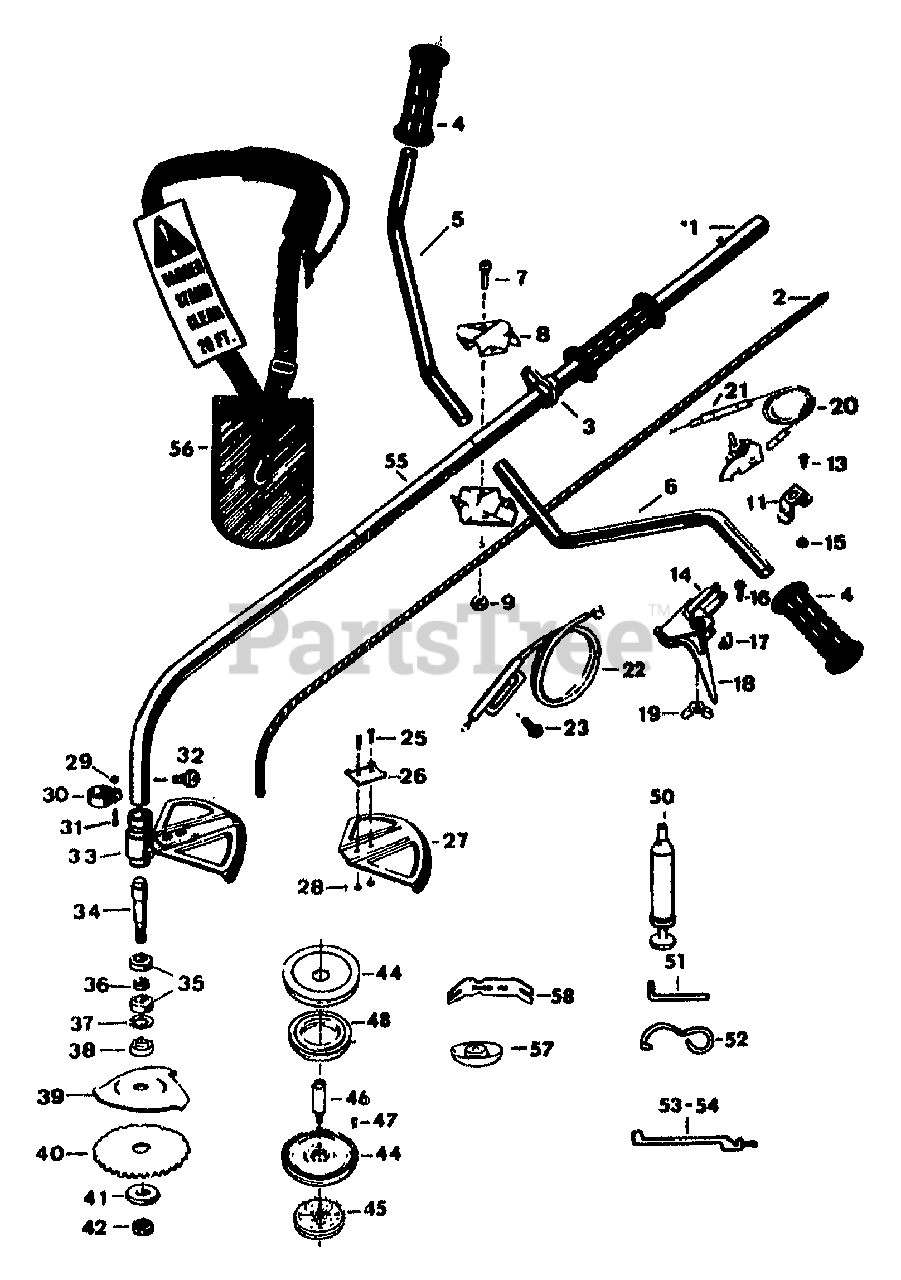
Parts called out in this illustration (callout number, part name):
1	HSG-DRIVESHAFT W/GRIP (INCL. GREASE FITTING)
2	SHAFT-DRIVE 5/16X57"
3	ASSM-SWIVEL
4	GRIP-HANDLEBAR
5	H/BAR-RH W/GRIPS
6	HANDLEBAR-LH W/GRIP
7	SCREW, SOCKET HD., 10-32, HANDLEBAR CLAMP
8	ASSM-CLAMP (INCL. 7 AND 9)
9	NUT, HEX, HANDLEBAR CLAMP
11	SWITCH-ON/OFF (INCL. BRACKET)
13	SCR-PHP M10-32X.75 ZP
14	KIT-CLAMP TRG. H205596
15	NUT-HH M10-32X.125
16	SCREW, HEX HD., 10-32X1, THROTTLE CONTROL
17	SPRING, THROTTLE CONTROL
18	ASSM-TRIGG H205532 (INCL. 16,17,19)
19	NUT, WING, 10-32, THROTTLE CONTROL
21	WIRE CONNECTOR & COVER
22	CABLE-THROTTLE
23	SCR W/SERRATED WASHER
25	SCR 1/4-20X1/2
26	CLAMP-GRASS/DUST SHIELD
27	ASSM-GRASS/DUST SHIELD
28	NUT-HF/LK 1/4-20 ZP
29	NUT-HF/LK 1/4-20 ZP
30	CLAMP-LOWER HEAD
30	KIT (INCL. 29-31)
31	SCR-HXSKT 1/4-20X.75
32	SCR #10-32X5/16
32	SCR-PHP M10-32X.375 STH ZP
33	ASSM-LWR HEAD W/KICK ST
34	ARBOR-LOWER (SQUARED)
37	RING-RETAINING
38	WASHER-CUP
39	BLADE-8" TRIKUT HOFFCO
40	BLADE-8" BRUSHCUTTER
41	WASHER-ARBOR 3/8
42	NUT W/NYLON INSERT 3/8-24
44	HOUSING-MONOFILAMENT HEAD
45	KNOB-RH MONOFILAMENT HEAD
46	ARBOR-MONOFILAMENT HEAD
47	LINE SAVER-MONOFIL HEAD
48	SPOOL-15'H2 #H211524
50	GUN-GREASE
51	WRENCH-ALLEN 3/16
52	LOWER HEAD TOOL
53	STRAP-TIE 7/8
54	STRAP-TIE 1"
55	DECAL-INST
56	HARNESS W/HIP PAD
57	KIT-GLIDE BALL
58	TEMPLATE-GAUGE(FILING)
